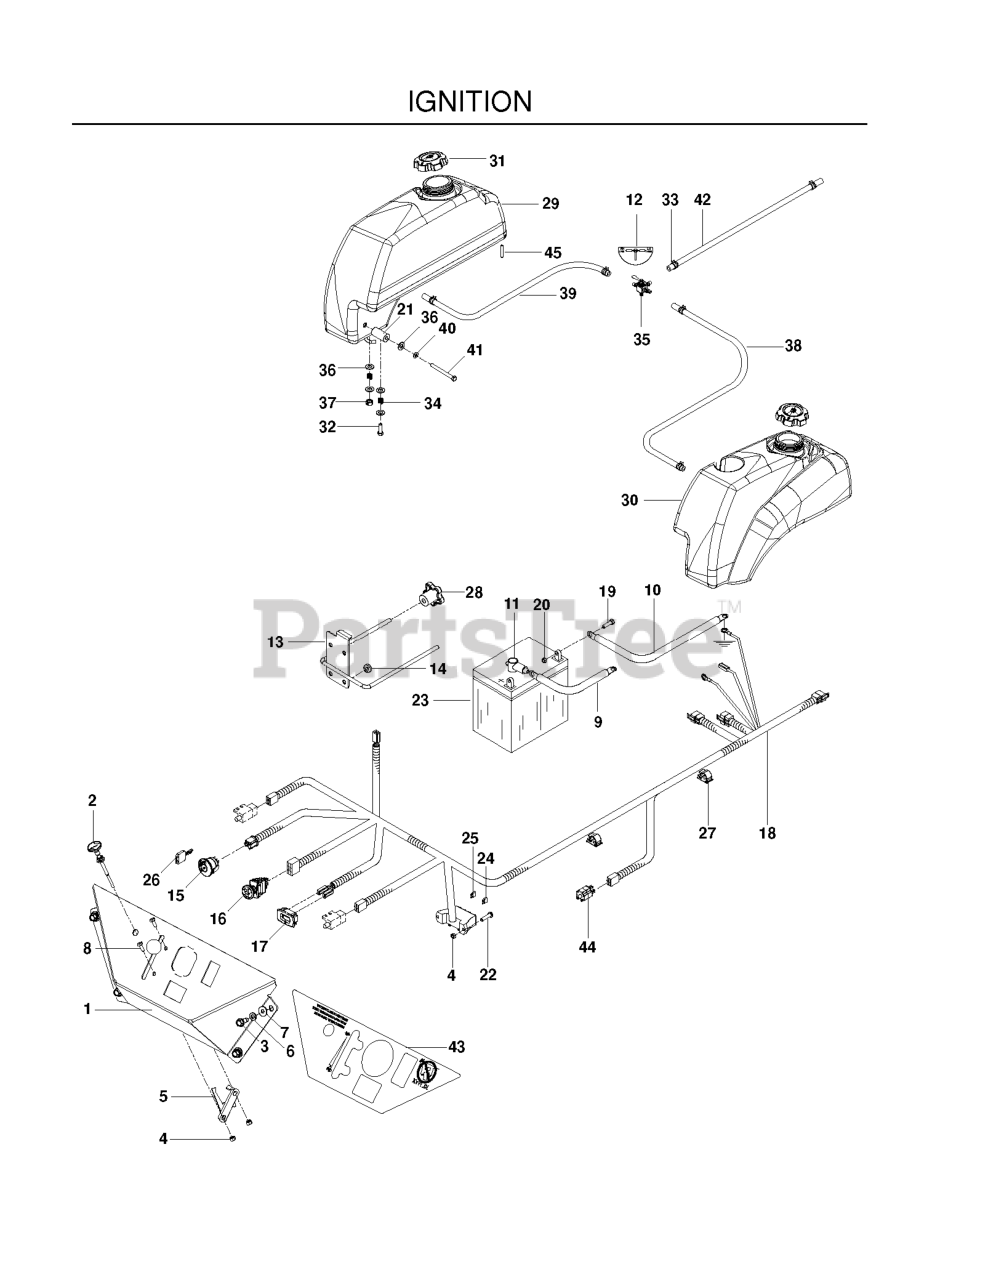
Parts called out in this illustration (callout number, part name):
1	CONSLE, ORANGE
2	CONTROL-CHOKE 57"
3	SCREW 1/4 X 5/8
4	NUT 10-24 NYLOC
5	THROTTLE CONTROL W/BALL KNOB
6	LOCKWASHER 1/4"
7	WASHER 1/4 FLAT
8	HCS #10-24 X 1/2
9	POST.CABLE LONG
10	CABLE-NEGATIVE
12	DECAL, FUEL VALVE
13	BATTERY HOLD DOWN
14	GROMMET, BUMPER
15	RP IGNITION SWITCH
16	SWITCH, PTO 10 AMP
17	HOUR METER
18	HARNESS, WIRING LZ/IZ
19	HCS 5/16C X 3/4
20	NUT 5/16 NYLOC
21	TANK SPACER
22	SCREW, #1--24 X 1/2 SLOTTED
23	BATTERY, 12 V 330 AMP
24	FUSE, 7.5 AMP 32 VOLT ATO
25	FUSE, 20 AMP 32 VOLT ATO
26	KEY
27	PUSH-MOUNT WIRE CLIP
29	FUEL TANK RT
30	LEFT TANK W/CUP HOLDER
31	FUEL CAP, HTC
32	HCS 5/16C X 1
33	HOSE CLAMP
35	FUEL VALVE
36	WASHER 5/16 FLAT
37	NUT 5/16C CENTERLOCK
40	WASHER.LOCK.HVY.HLCL.SPR.5/16
41	HCS 5/16C X 4
42	FUEL LINE 13"
43	DECAL, CONSOLE
44	SWITCH, BRAKE 3P
45	STUD, 5/16C
